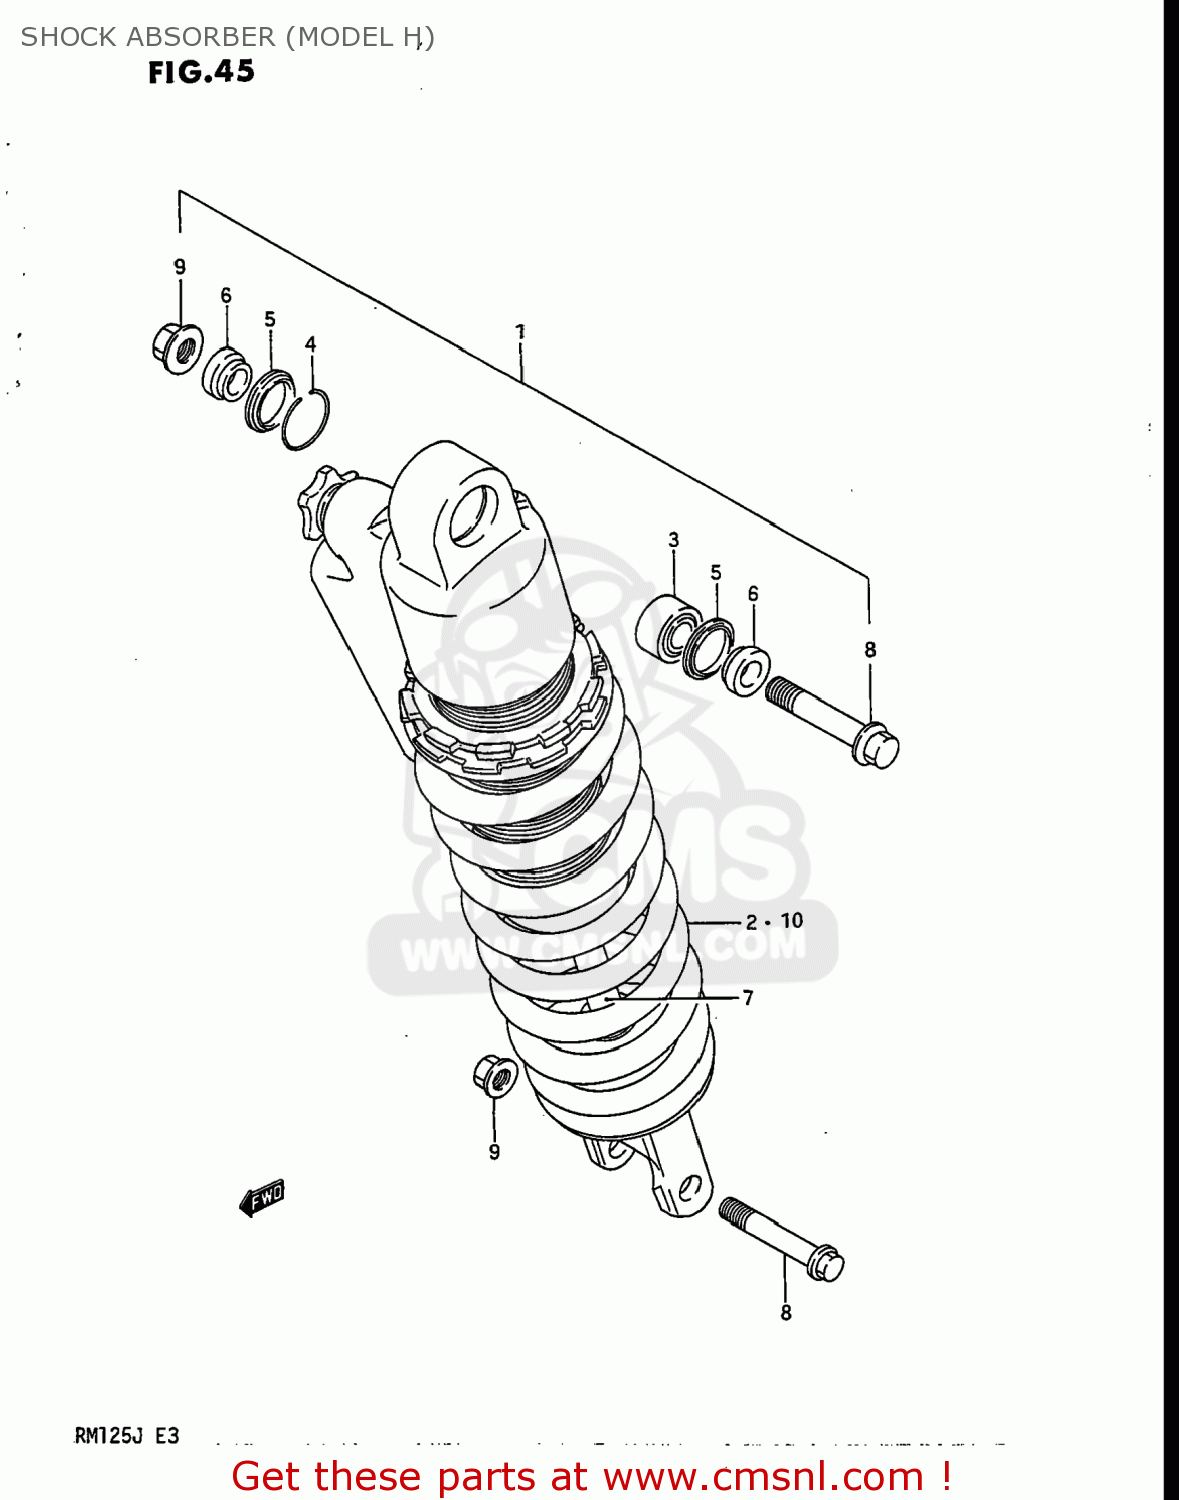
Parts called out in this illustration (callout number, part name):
1	ABSORBER ASSEMBLY,REAR SHOCK
2	SPRING
3	BEARING,RR CUSHION LEVER
4	RING
5	DUST SEAL
6	SPACER
7	ROD,PISTON
8	BOLT,REAR SHOCK ABSORBER
9	NUT
10	SPRING
